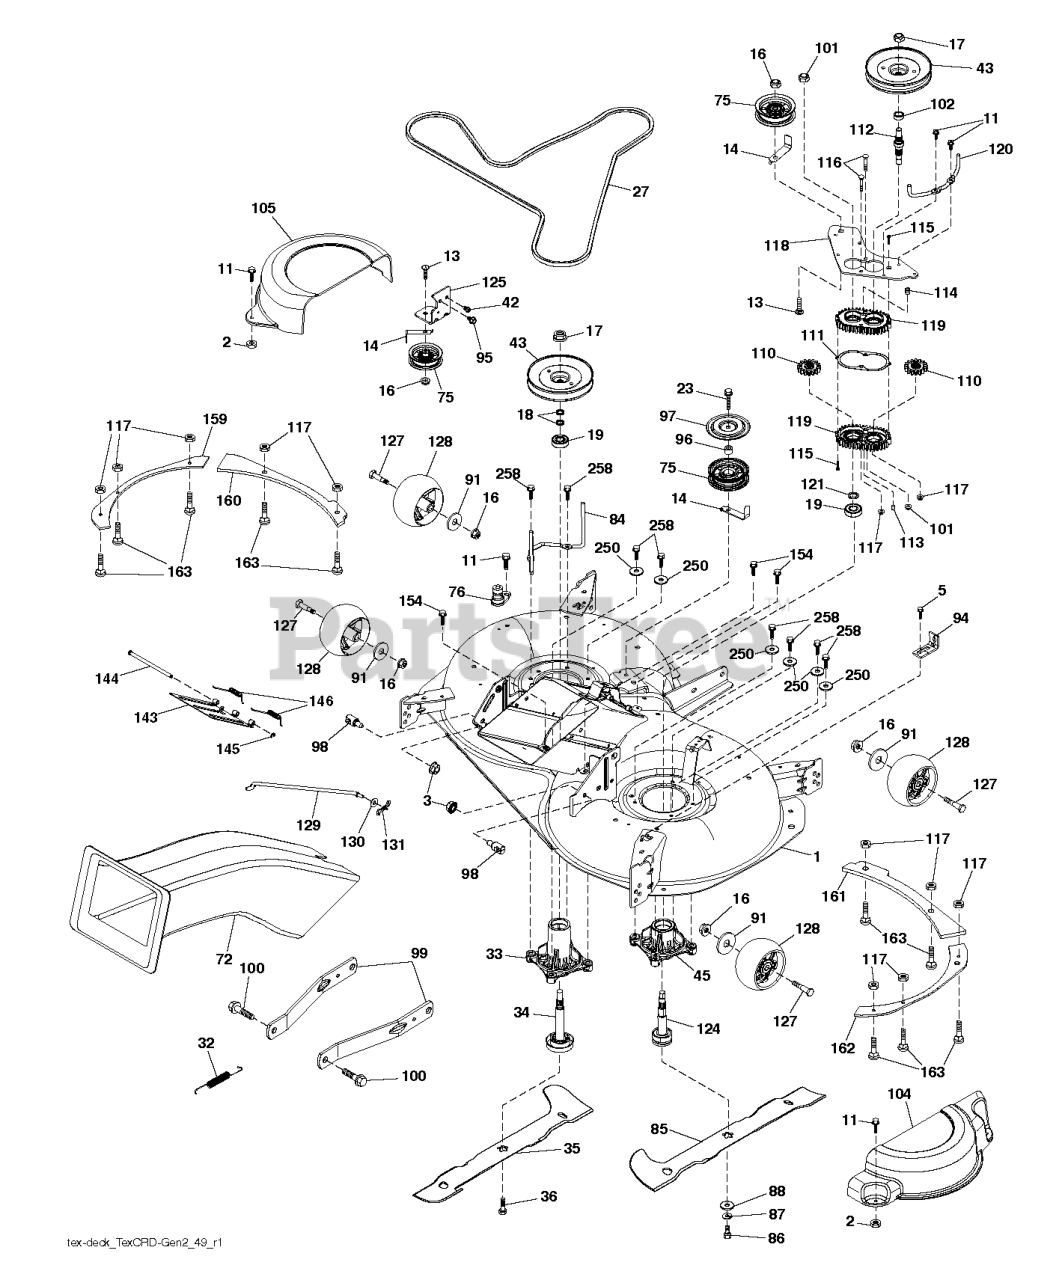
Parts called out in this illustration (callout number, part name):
1	DECK SVC 107HP.EZMUL.498
2	PALNUT 1/4
3	NUT LOCK HEX FLANGE 5/16-18
5	BOLT.5/16HEX.WHS.HD
11	SCREW.1/4-20X5/8
13	BOLT.3/8-16X1.50
14	KEEPER, BELT IDLER
16	NUT LOCK FLG 3/8-16 UNC
17	NUT.FLANGE.LOCK.TOP
18	WASHER.SPACER.MANDREL
23	SCREW LT
27	BELT BELT. ELECTRIC MOWER DRIV
32	SPRING 107CM & 97CM ELECTRIC D
33	RP.HOUSG.MAND.REV.TALL.N/GRS
34	RP.SAFT ASM.REV.TALL.N/GREASE
35	BLADE.107.LH.SINGLE.NON.QD
36	BOLT.WASHER.ASM.7/16-2
42	SCREW
43	PULLEY PULLEY MANDREL 5.438 PD
45	RP HOUSING.MANDREL.REV.REVS.
72	RP.CHUTE 107/97 TEX GENII
75	FLAT IDLER PULLEY
76	PORT.WASHOUT
84	KEEPER KEEPER. LH MANDREL BELT
85	BLADE.107.RH.SINGLE.NON.QD
87	LOCKWASHER
88	WASHER.BLADE
91	WASHER
94	BRKT.CLUTCH.CABLE
95	SCREW, 3/8-16X3/4
96	SPACER
97	PROTECTOR
98	STUD.FASTNER.W/ANTI-ROTATE
99	ARM.SUSPENSION.MOWER.R
100	BOLT.SHOULDER
101	NUT.CROWNLOCK.9/16 -18.UNC
102	SPACER BEARING
104	COVER.MANDREL.107.RH.GEN.2
105	COVER.MANDREL.107.LH.GEN.2
110	CRD.SPUR.GEAR
111	GASKET GASKET GEARCASE
112	SHAFT SHAFT. CRD GEARCASE ADAP
113	PLUG PLUG OIL
114	VALVE VALVE RELIEF
115	SCREW
116	BOLT.CARIGE.SS.1/4-20X1.75GR5
117	NUT T
118	ARM ARM. CLUTCHING 107 TEX CRD
119	GEARCASE GEARCASE SUBASM
120	KEEPER KEEPER. RH MANDREL BELT
121	WASHER WASHER
124	SUB.ASM.REVERSE.THREAD.REV
125	BRACKET
127	BOLT.SHOULDER.3/8-16X3-5/8.
128	RP WHEEL. GUAGE RALLY
129	ROD ROD. SWAY CRD GEN II
130	WASHER
131	PIN.COTTER.5/16.BOW TI
143	COVER DOOR.107 CM CRD EZ MULCH
144	PIN PIN.HINGE
145	E-RING.5/16"
146	SPRING SPRING: EZ MULCH DOOR
154	SCREW T-30 1/4-20 X
159	REINFORCE.PLATE.LHS.BOLT.431
160	REINFORCE.PLATE.LH.FT.X431
161	REINFORCE.PLATE.RH.FRT.X431
162	REINFORCE.PLAT.RH.SD.BLT.X431
163	BOLT
258	BOLT.HEX.WASHR.HED.313-18X1.19
